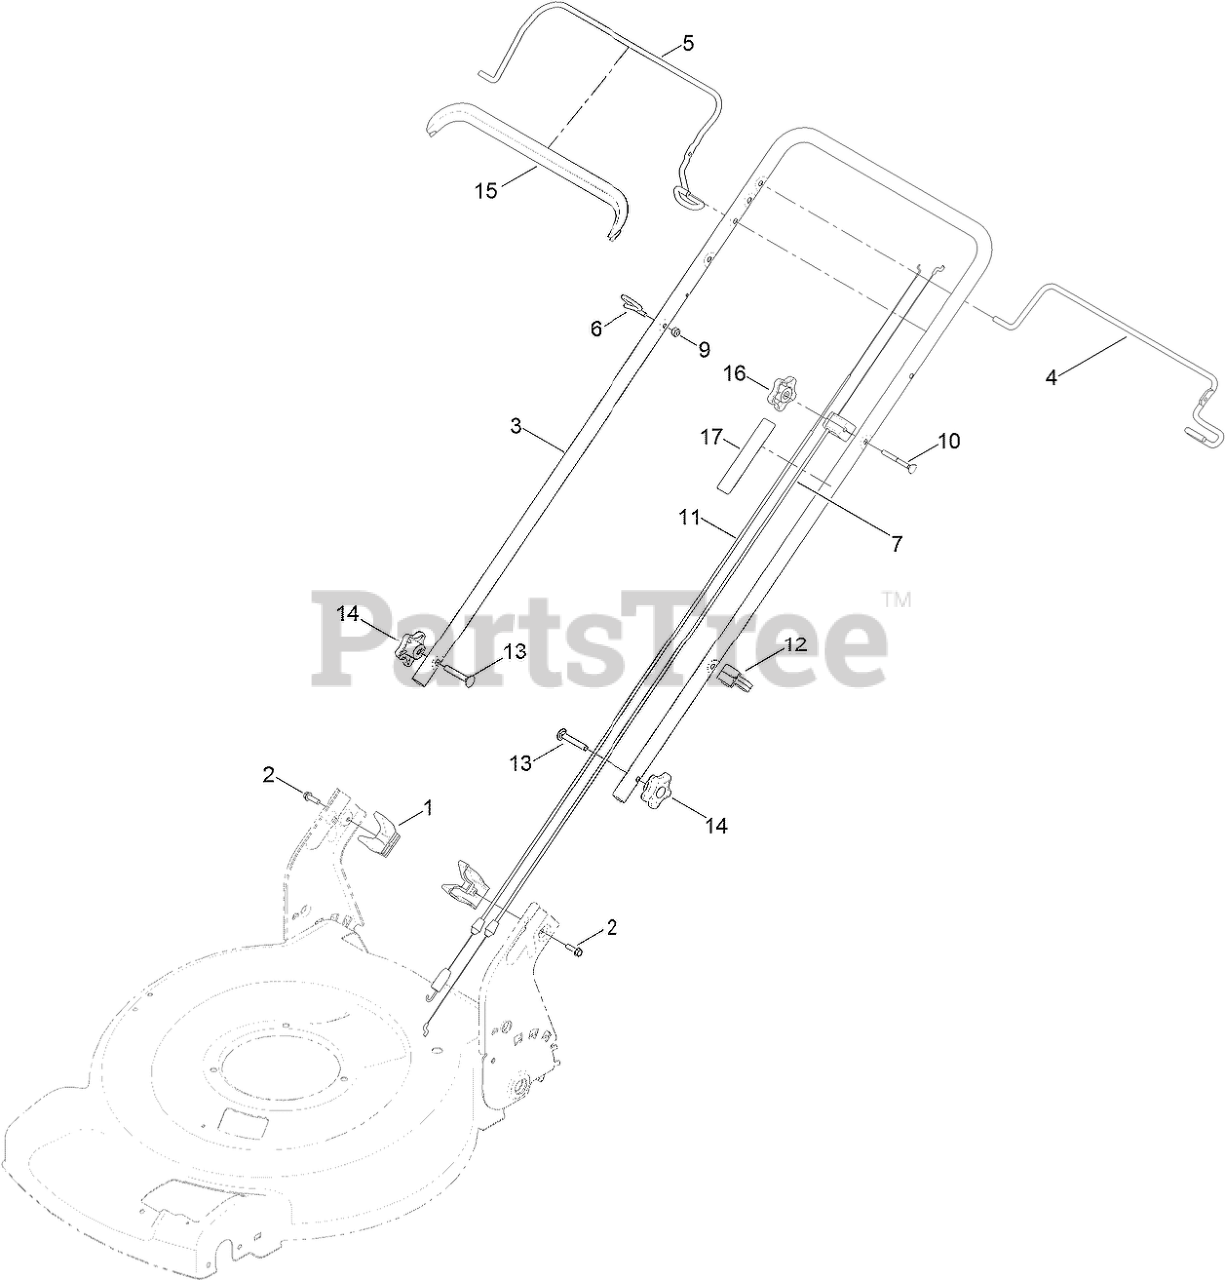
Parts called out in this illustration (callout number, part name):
1	ANCHOR-BAG
2	SCREW-HWH
4	BAIL-TRACTION
5	BAIL-BRAKE
6	GUIDE-ROPE
7	CABLE-BRAKE
9	NUT-LOCK, NI
10	SCREW-HANDLE
11	CABLE-TRACTION
12	GUIDE-CABLE
13	Screw-CARR
14	KNOB-HANDLE
15	COVER-BAIL
16	KNOB-HANDLE, LOCKING
17	DECAL-TRACTION, ADJUST
